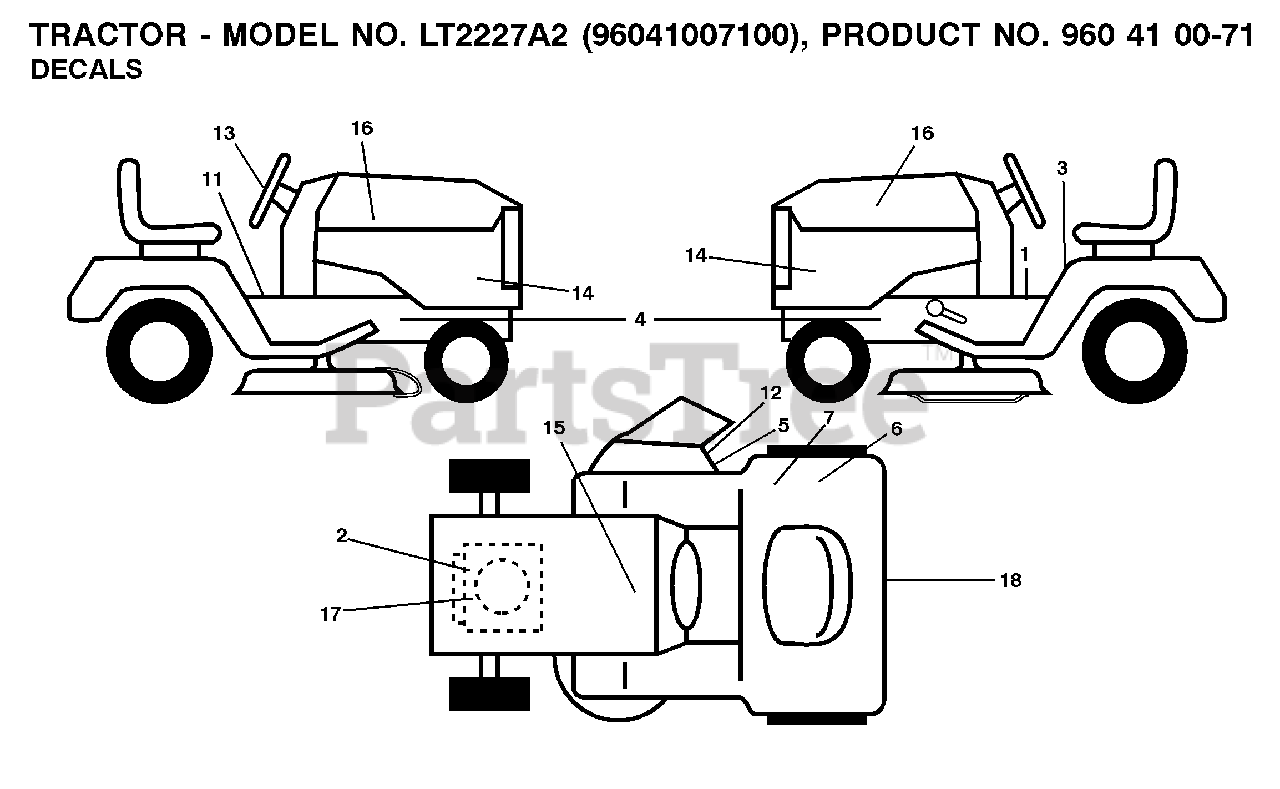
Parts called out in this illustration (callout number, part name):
1	DECAL PARK BRAKE
5	DECAL, DEFLECT WARNING
7	DECAL.80 DBA.AUSTRALIA
8	DECAL.MOWER.SCH.48/54
12	DECAL.INTERNATIONL.CUTFINGER
15	DECAL BTRY SYMBOLS
